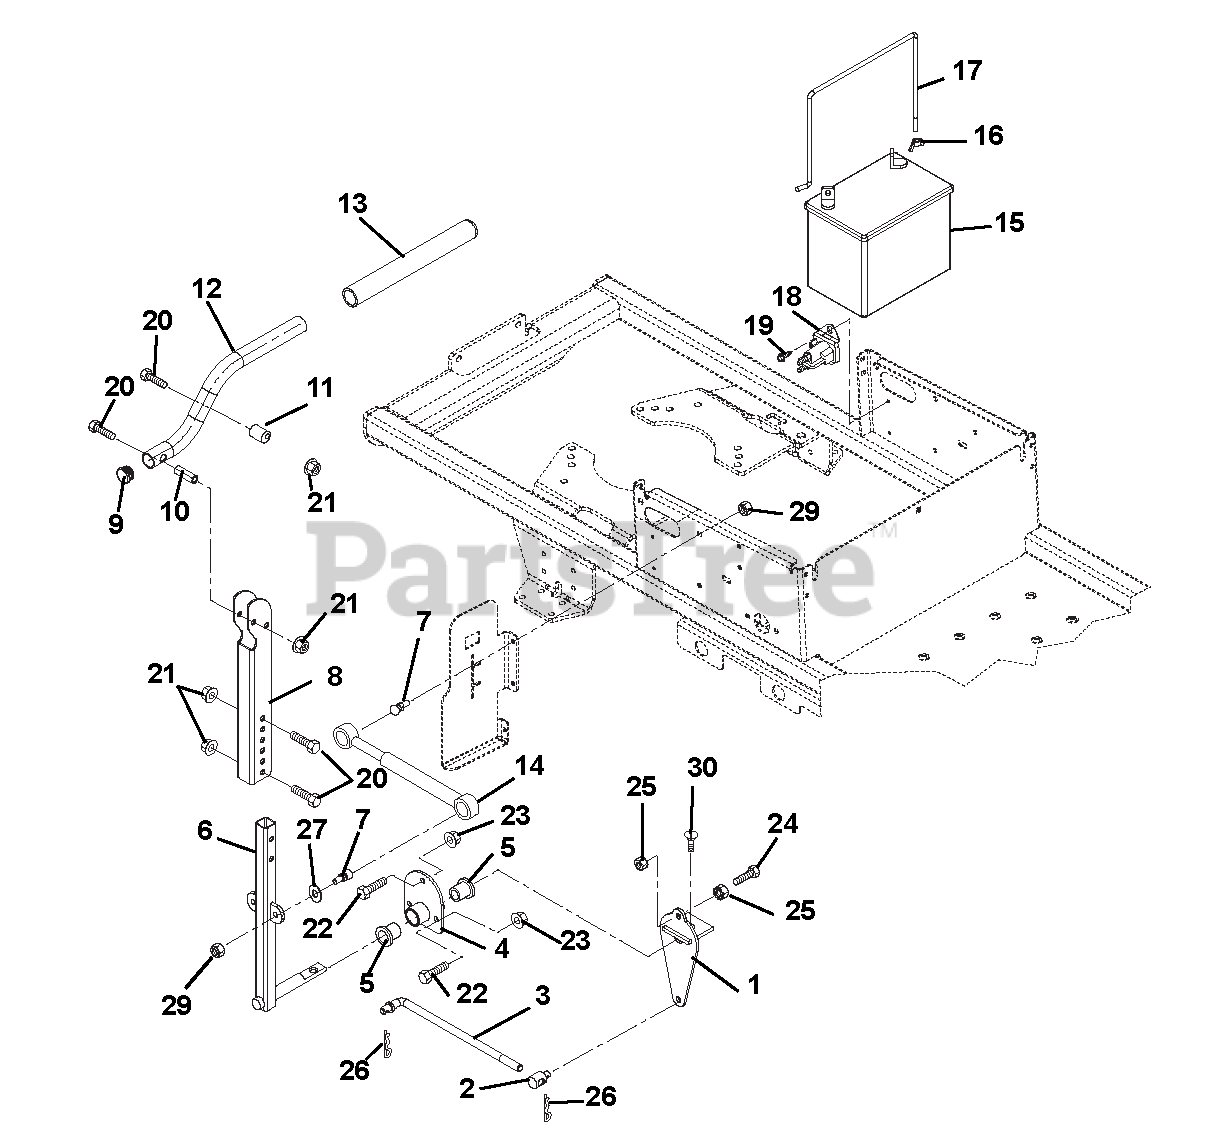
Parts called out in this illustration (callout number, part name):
1	CONTROL LINK WMT
2	PIVOT, ROD (TRUNNION ) .50
3	LINK,WIREFORM
4	WMT, STEERING BUSHING
5	BUSHING-1"X.75"X1"
6	WMT, CONTROL ARM
7	STUD- BALL
8	CHANNEL,UPPER HANDLEBAR
9	CAPLUG, HANDLEBAR
10	BSHG, SPCR .330X.500X1.01 PM
11	BSHG,ECCEN .328X.750X1.01 PM
12	HANDLE BAR
13	GRIP - HANDLEBAR
14	DAMPER, CONTROL
15	BATTERY, 300 CCA 10U1L
16	NUT-LK WING .250-20 YWZC
17	BATTERY ROD
18	SOLENOID
19	@SCR-TAP .25-20X.37 HWH YWZ TR
20	@BLT-HEX .31-18X1.75 GR5 YWZC
21	@NUT-LK-NYL-FLG .31-18 YWZC
22	@BLT-HEX .31-18X.75 GR5 YWZC
23	@NUT-LK-NYL-FLG .31-18 YWZC
24	BLT-HEX .38-16X3.00 GR5 FTH YZ
25	@NUT-SPNLK-FLG .375-16 YWZC
26	PIN-HAIR, ENDRIES #25 YWZC
27	@WSHR-LK .31X.078 REG YWZC
28	NUT- JAM .312-18 YWZC
29	@NUT-LK-TOP-FLG .31-18 YWZC
30	BOLT, 3/8-16X1 FSHCS PLN
